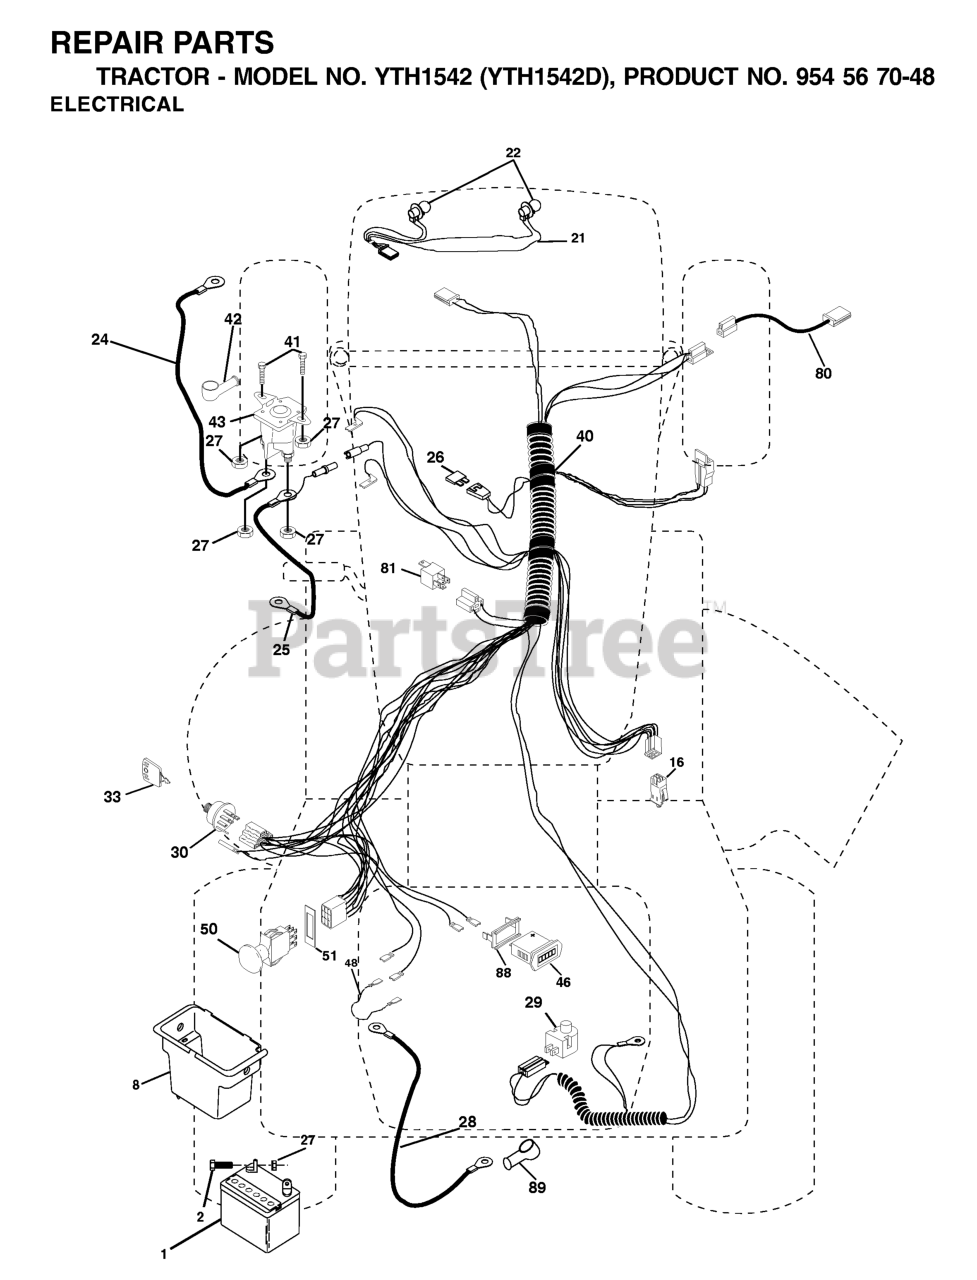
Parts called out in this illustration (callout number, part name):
1	Battery 12 Volt 25 Amp
2	BOLT.HEX.1/4.X.3/4.DICHROMATE
8	BOX.BATTERY.FENDER
16	SWITCH INTERLOOK PUSH-IN
21	HARNESS.ASM.LIGHT WSL
24	BATTERY CABLE GT
25	CABLE BATTERY
26	FUSE 20AMP
27	NUT
28	CABLE T
29	PLUNGER SWITCH (COLOR:OLIVE)
30	IGNITION SWITCH
33	KEY MLD GEN DELTA
40	HARNESS IGN.
41	BOLT
42	TERMINAL COVER
43	SOLENOID
46	HOUR METER
48	ADAPTER.AMMETER
50	RP.PTO.SWITCH.8 TERMINAL.BLACK
51	FRAME RETAINING RING
80	HARNESS, CLUTCH
81	RELAY.ASSY.T
88	BRACKET SNAP-IN HOURMETER
89	COVER TERMINAL
